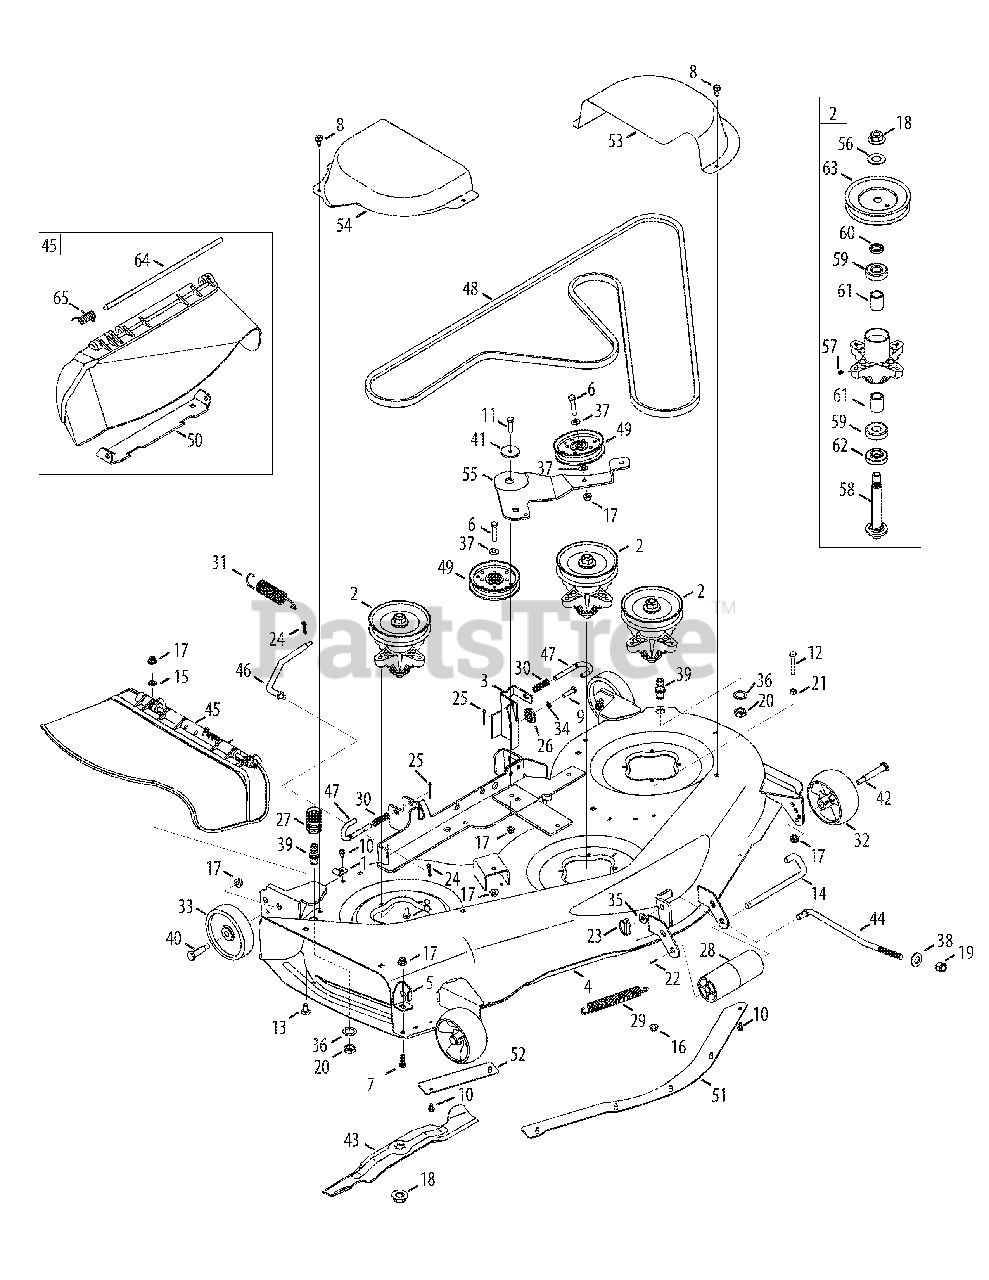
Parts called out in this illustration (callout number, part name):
1	Retainer Hook Brkt.
2	Spindle Assembly
3	Deck Hanger Bracket Ass'y
5	Chute Deflector Stop
6	Hex Screw 3/8-16 x 1.75
7	Screw, 3/8-16 x 1.0
8	Hex Wash Hd. Tapp Screw. 5/16-18 x .75
9	Hex Bolt 5/16-18 x 1.25
10	Hex Wash S-Tapp Screw 1/4-20 x .50
11	Hex Bolt 3/8-16 x 1.25
12	Hex Hd Cap Screw. 5/16-18 x 2.0 Gr. 5
13	Short Neck Carriage Bolt 3/8-16 x .75
14	Roller Pin
15	Push Nut 3/8
16	Flange Locknut 5/16-18 Gr. F, Nylon
17	Flange Lock-Nut 3/8-16 Gr. F Nylon
18	Flange Nut 5/8-18
19	Flexlock Nut 1/2-13
20	Hex Nut M16-1.5 DIN 936
21	Hex Nut 5/16-18 hd. (Gr. 5)
22	Cotter Pin 3/32 x 1.0
23	Lynch Pin, .1875
24	Bow Tie Cotter Pin
25	Cotter Pin 1/8" Dia x 1.25
26	Deck adjustment Gear
27	Water Nozzle Adap tor
28	Front Roller
29	Extension Spring .94 x 6.74
30	Compression Spring .535 OD x 1.751 Lg.
31	Extension Spring 1.15 x 5.99
32	Deck Wheel 5.0
33	Wheel Ass’y - Deck 5" x 1.38"
34	L-Wash 5/16 ID
35	Flat Washer .531 ID x 1.25 OD x .100
36	L-Washer Internal
37	Flat Washer .406 ID x .875 OD x .059
38	Cupped Washer .63 x 1.25 x .18
40	Shoulder Bolt .498 Dia x 1.53 x 3/8-16
41	Spacer, Shoulder .884 x .190
42	Shoulder Screw
44	Front Deck Lift Rod
45	Chute Ass'y
46	Deck Sway Rod
47	Deck Release Pin
48	V-Belt
49	Idler Pulley
50	Chute Bracket
51	Deck Skirt Center
55	Chute Bracket
56	Flat Washer .760 ID x 1.50 OD x .120
57	Grease Fit ting
58	Spindle Shaft
59	Ball Bearing 20 x 47 x 14:6204:DS
60	Spacer .790 x 1.25 x 1.75
61	Spacer .800 x 1.10 x 1.322
62	Spacer .79 x 1.82 x .55
64	Hinge Pin .3125 x 7.96
65	Torsion Spring .40 x 1.0
